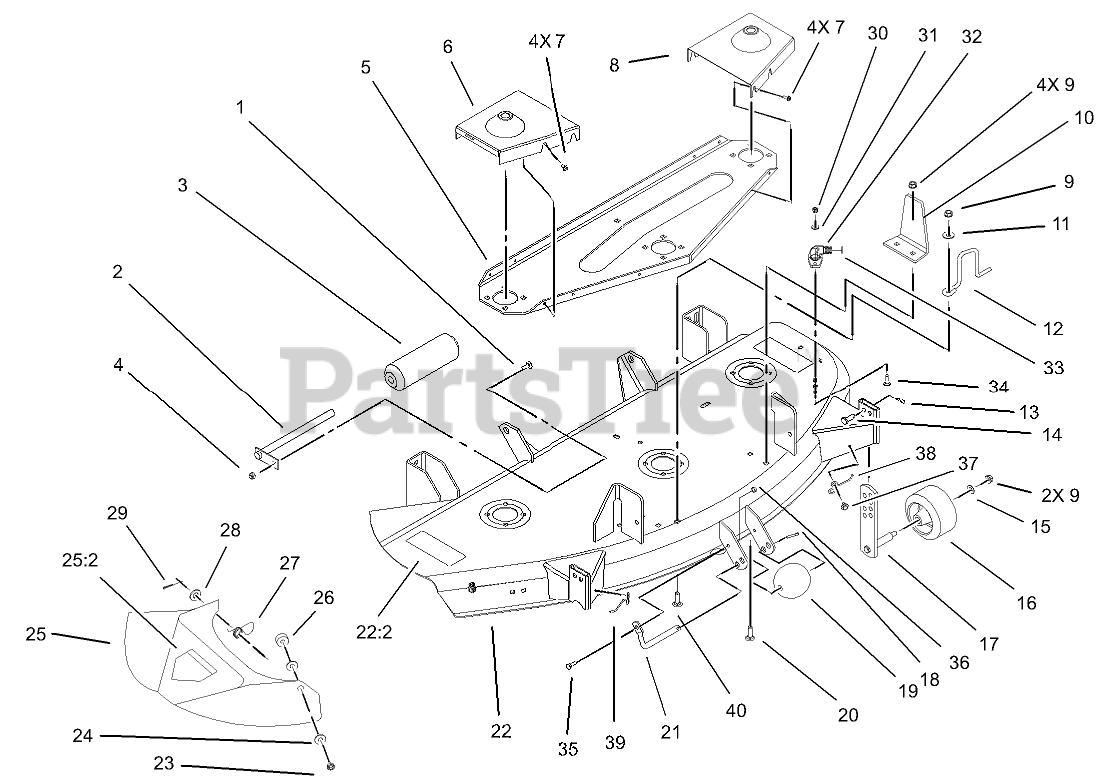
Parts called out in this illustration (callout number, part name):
1	BOLT-CARR
2	ROLLER-SHAFT
3	ROLLER-ANTI SCALP
4	NUT-LOCK, NI
5	PLATE-REINFORCE
6	COVER-BELT, RH
7	SCREW-HHFTF
8	COVER-BELT, LH
9	NUT-LOCK, NI
10	BRACKET-GUIDE
11	WASHER
12	GUIDE-BELT
13	PIN-HAIR
14	PIN-CLEVIS
15	WASHER-FLAT
16	WHEEL-GAGE
17	GAGE-WHEEL
18	PIN-COTTER
19	ROLLER
20	BOLT-CARR
21	Shaft-Roller
22	48" DECK/DECAL ASM-5XI,EU
22:2	DECAL-DANGER
23	NUT-HJ
24	WASHER
25	CHUTE ASM
25:2	DECAL-DANGER
26	BUSHING-PIVOT
27	SPRING-DEFLECTOR
28	WASHER-FLAT
29	PIN-COTTER
30	NUT-LOCK, NI
31	WASHER-FLAT
32	FITTING-WASHOUT
33	O-RING
34	BOLT-CARR
35	SCREW-HH
36	NUT-LOCK, NI
37	SCREW-HHFTF
38	SPRING-GAGE WHEEL, LH
39	SPRING-GAGE WHEEL, RH
40	SCREW-CARR
